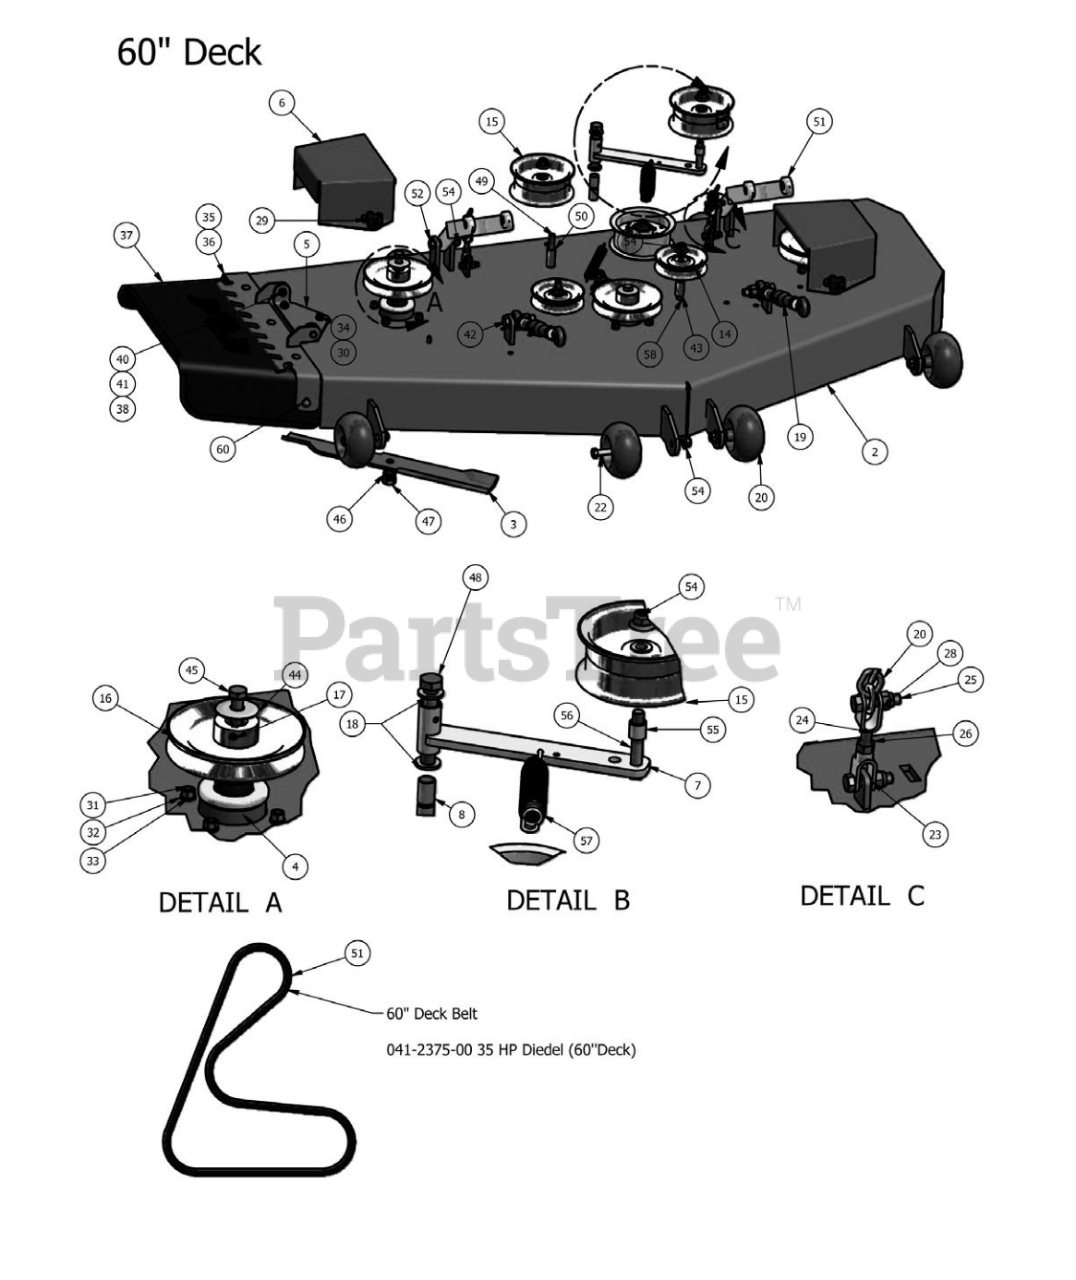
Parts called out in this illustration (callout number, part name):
1	60" Deck Complete Assembly with Spindles
2	60" Deck Shell Only
3	60 Inch Fusion Blade
4	Double Bearing Spindle Assembly
5	Discharge Chute Hanger
6	Plastic Pulley Cover
7	Deck Idler
8	5/8 x 1 1/8" Brass Bushing
9	1/2" x 3" Hex Bolt
11	1" Collar Spacer
12	1/2-13 Nylon Flange Nut-Orange
14	4 3/4" Idler Pulley
15	5 3/4" Deck Idler Pulley
16	6 1/4" Drive Pulley
17	5/16" Set Screw
18	.635 ID Plastic Washer
19	Turnbuckle (Top Link)
20	Anti-Scalp Rollers
21	Anti-Scalp Rollers Complete Assembly
22	1/2" x 4" Bolt (Grade 8)
23	Female Yoke
25	3/8" x 1 1/2" Hex Bolt
26	3/8" Hex Nut
27	4" Chain Assembly Diesel
28	3/8 Nylock Nut
29	5/16" Knob
30	3/8" x 3/4" Hex Bolt
31	3/8" x 1 1/4" Hex Bolt
32	3/8" Lock Washer
33	3/8" Hex Nut
34	3/8" Flange Nut
35	60" Lower Hanger
36	60" Discharge Chute Upper Hanger Plate
37	Rubber Discharge Chute (Rubber Only)
38	.360 ID Plastic Washer
39	Complete Assembly Rubber Discharge Chute
40	5/16" x 1" Hex Bolt
41	5/16" Nylock Flange Nut
42	5/8" x 2 1/2" Hex Bolt
43	Pulley Spacer
44	Cup Washer
45	1/2" x 1 1/2" Hex Bolt
46	5/8" Lock Washer
47	5/8-18 x 1 1/2 GR 8 Hex Bolt
48	5/8" x 4" Hex Bolt
49	1/2-13 x 3 1/2 GR 5 Hex Bolt
50	1 3/4" Pulley Spacer
51	Deck Arm Assembly
51	Deck Belt 60" Deck
52	1/2" x 2 1/2" Hex Bolt
53	1/2" Flange Nut
54	1/2-13 Nylon Flange Nut-Orange
55	3/4 OD x 1/2 ID x 3\4 Length
56	1/2 x 3" Bolt
57	Deck Idler Spring
58	1/2 x 3 1/2 Flange Bolt Grade 8
60	5/16" x 1 1/4" Carriage Bolt
